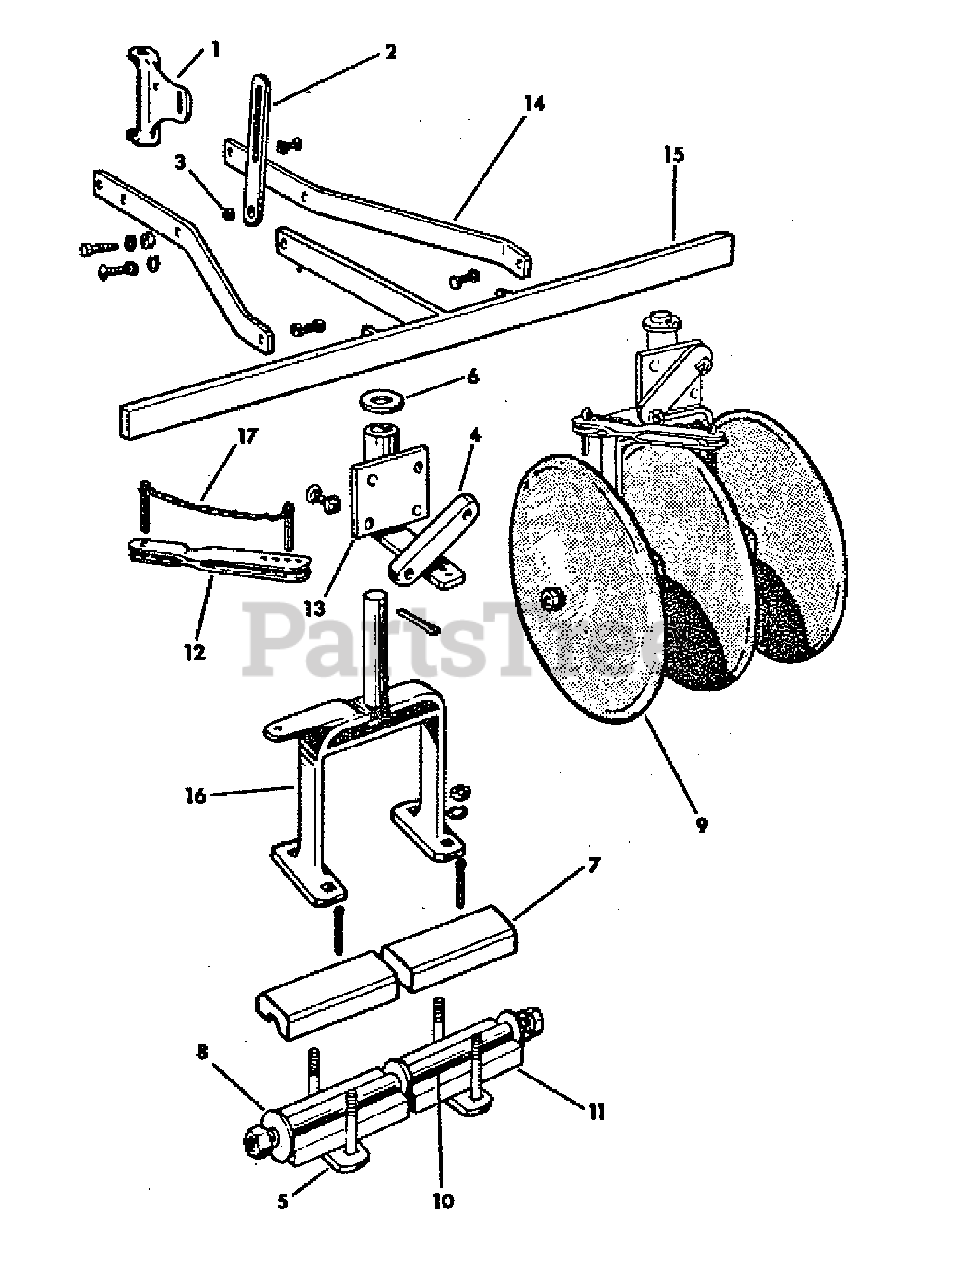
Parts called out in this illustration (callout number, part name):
1	END, Draw Bar
2	LINK, Tilt Adjusting
3	LINK SPACER, Tilt Adjusting
4	CLIP, Clamp
5	CLIP, Bearing
6	WASHER, Post
7	BLOCK, Bearing (Upper)
8	SPACER, Disc
10	BOLT, Machine (Axle)
11	BLOCK, Bearing (Lower)
12	STRAP ASSEMBLY, Angle Adjusting
13	CLAMP ASSEMBLY
14	BAR, Draw
15	BAR ASSEMBLY, Cross
16	ARCH ASSEMBLY
